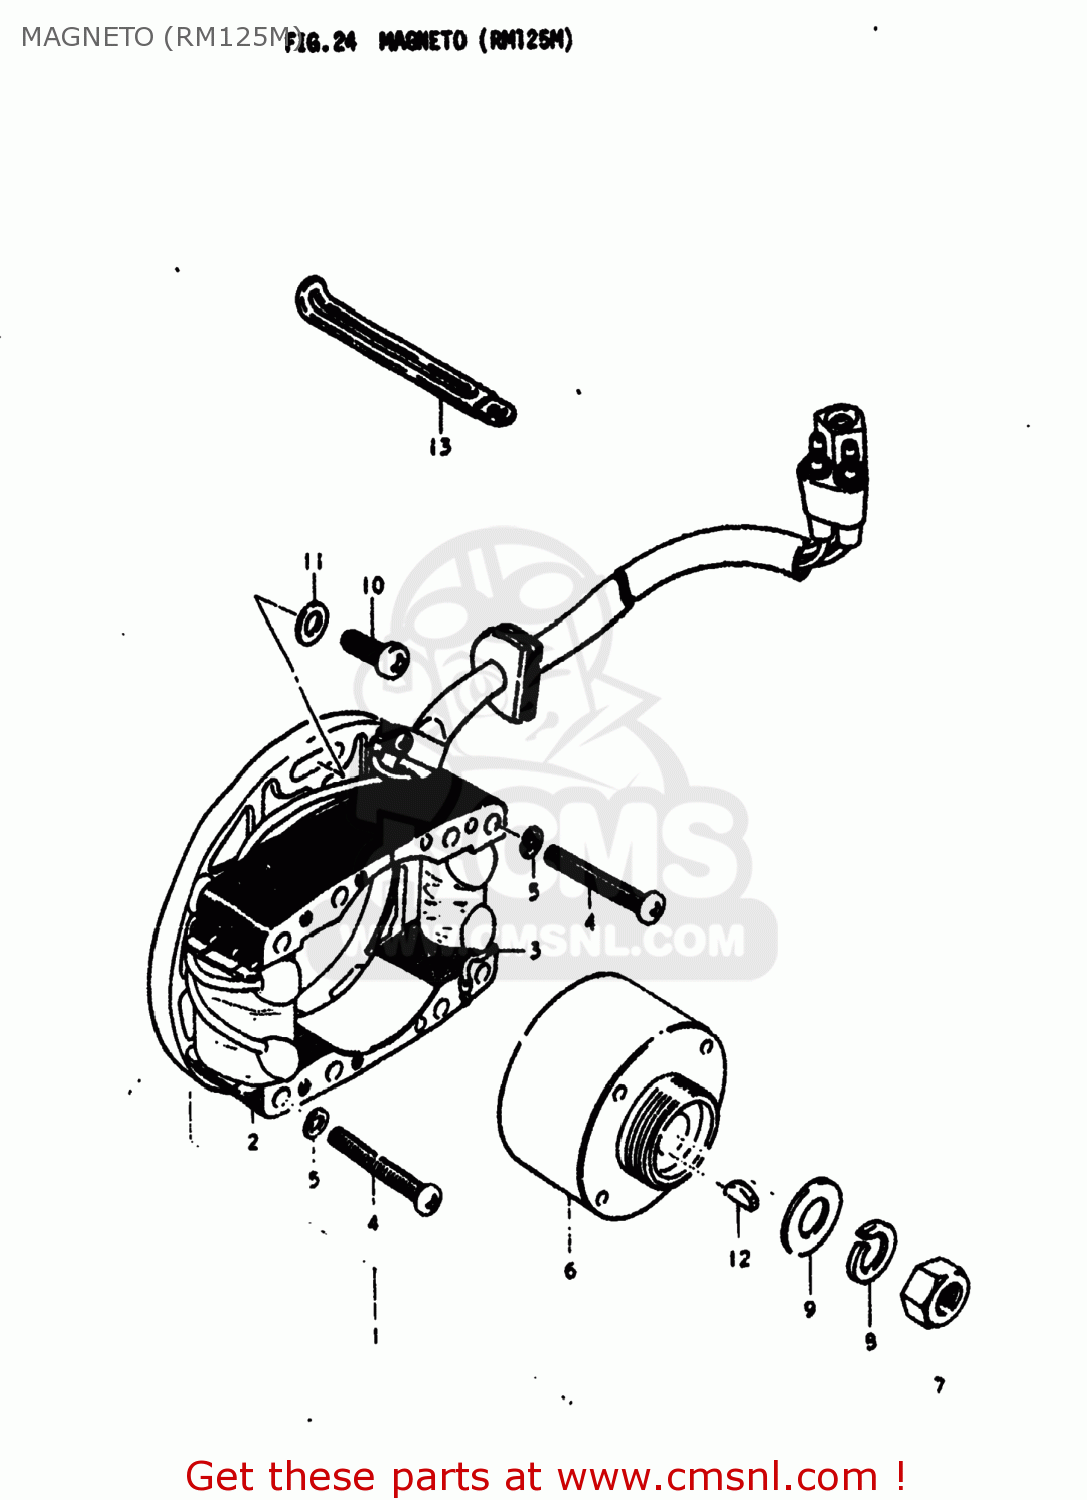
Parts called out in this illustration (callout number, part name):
1	MAGNETO ASSEMBLY
2	COIL
3	COIL,PULSER
4	SCREW
5	LOCK WASHER
6	ROTOR ASSEMBLY
7	NUT (10MM)
8	LOCK WASHER
9	WASHER
10	SCREW
11	WASHER
12	KEY
13	CLAMP
